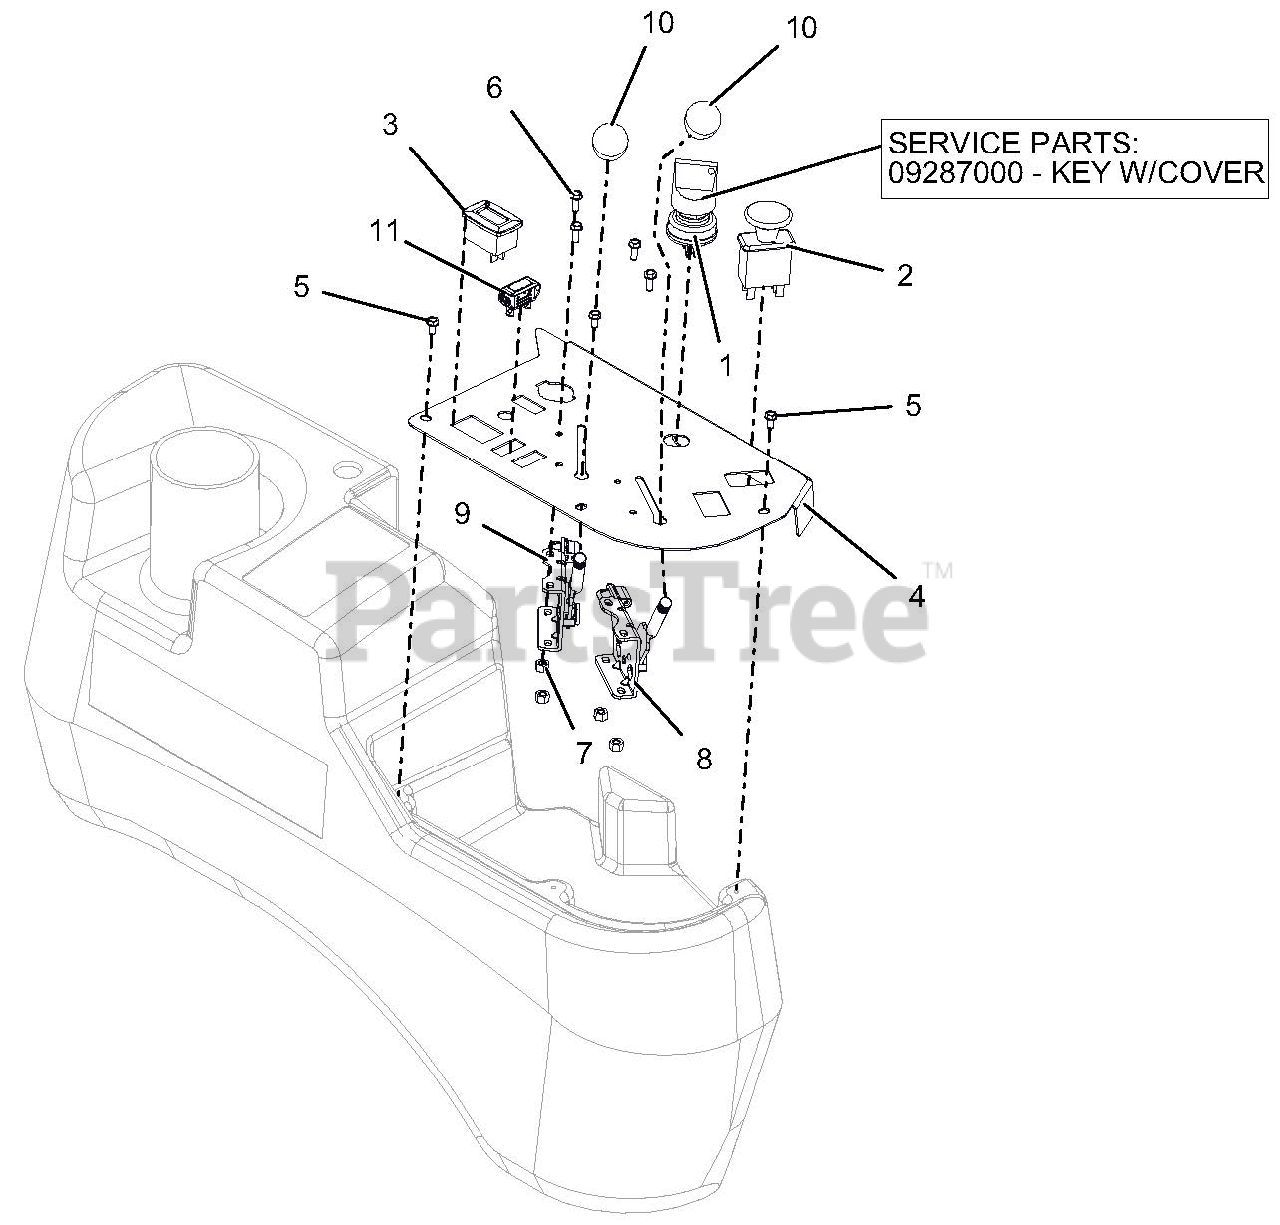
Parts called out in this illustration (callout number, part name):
1	SWITCH, IGNITION
1	KEY W/COVER
2	SWITCH, CLUTCH
3	METER, HOUR W/MAINTENANCE
4	PANEL, CONTROL
5	SCR-MCH 10-24X.38 HWHSTAINLESS
6	@SCR-MCH 10-24X.50 HWH YWZC
7	NUT-LK-NYL #10-24 YWZC
8	CABLE, PRO-CONTROL THROTTLE
9	CABLE, PRO-CONTROL THROTTLE
10	KNOB, CONTROL BLACK .38-16X.50
11	LIGHT, INDICATOR
